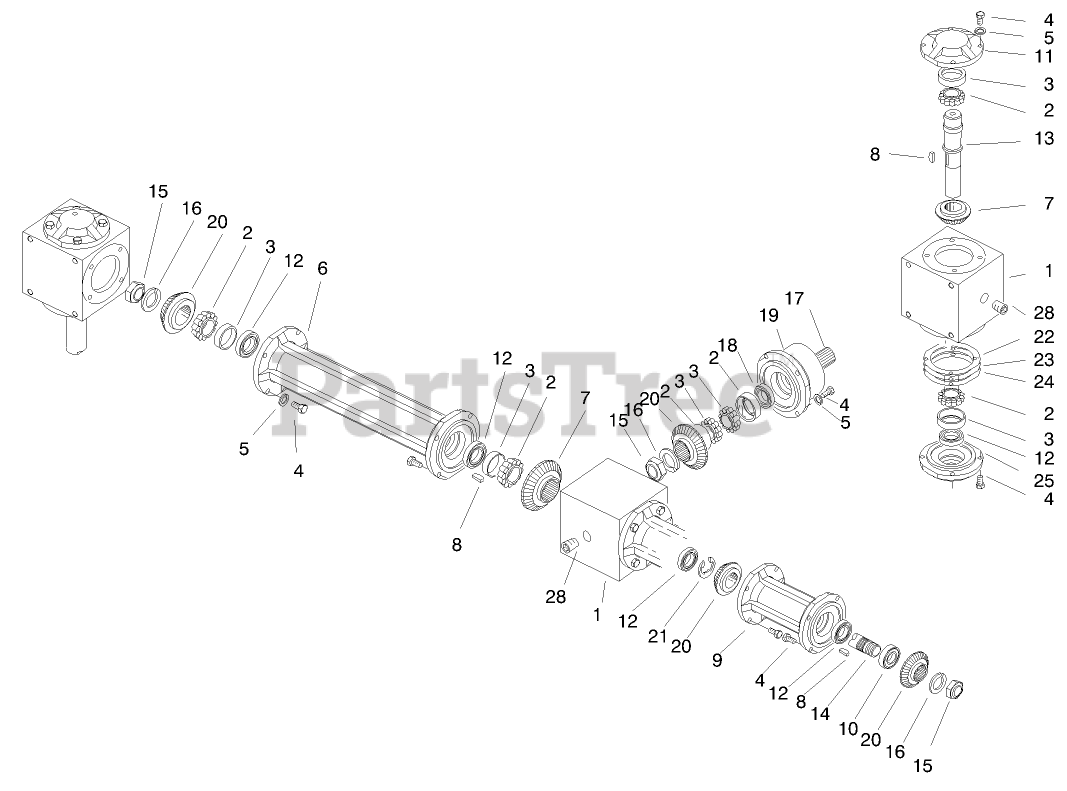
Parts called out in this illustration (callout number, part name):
1	HOUSING
2	BEARING - CONE
3	Cup
4	SCREW - HH
5	WASHER - LOCK
6	Connector-Hub
7	Gear-RH
9	Connector-Hub
10	BEARING - BALL
11	CAP - BLANK
12	Seal
13	Shaft-Thru
14	SHAFT
15	NUT - LOCK
16	WASHER - LOCK
17	SHAFT - HUB
20	PINION - LH
21	RING - RETAINING
22	Gasket-.015
23	Gasket-.005
24	GASKET - .003
25	CAP - THRU
26	I.d. Tag
27	I.d. Tag Cover
28	PLUG (OBS, C/R TO 281-10)
